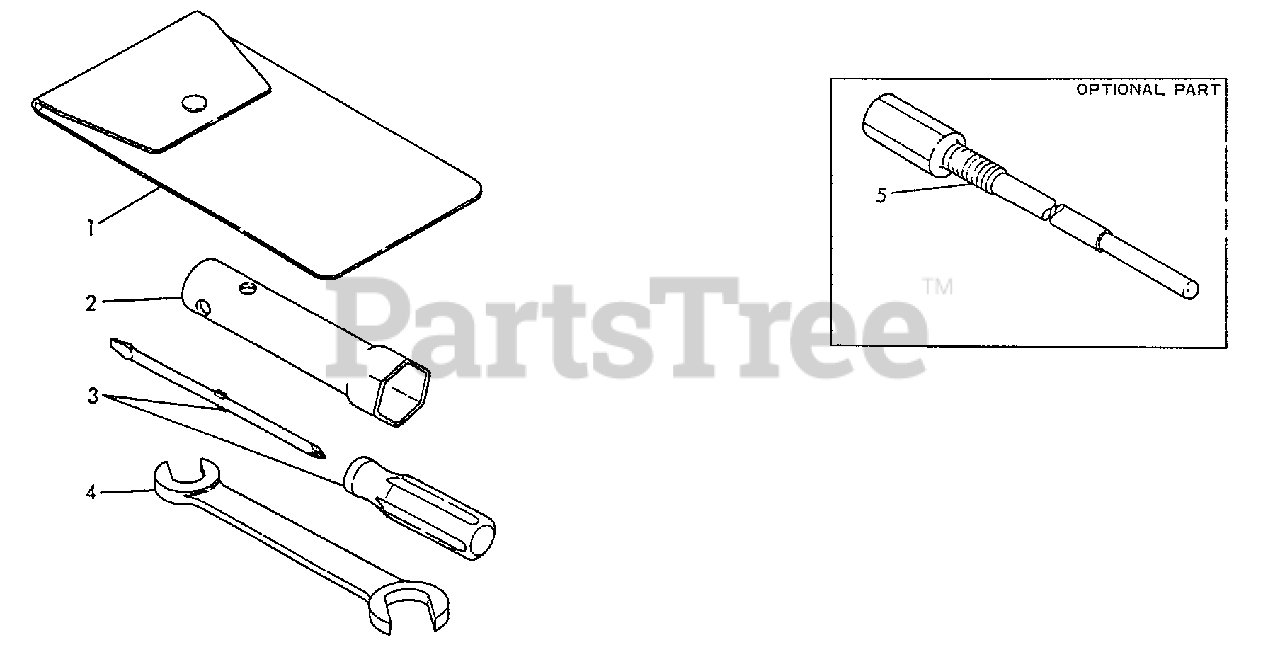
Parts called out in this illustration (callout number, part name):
1	BAG, TOOL
2	SOCKET WRENCH - 21mm
3	SCREWDRIVER
4	SPANNER - 10X12mm
5	REMOVER, ROTOR
